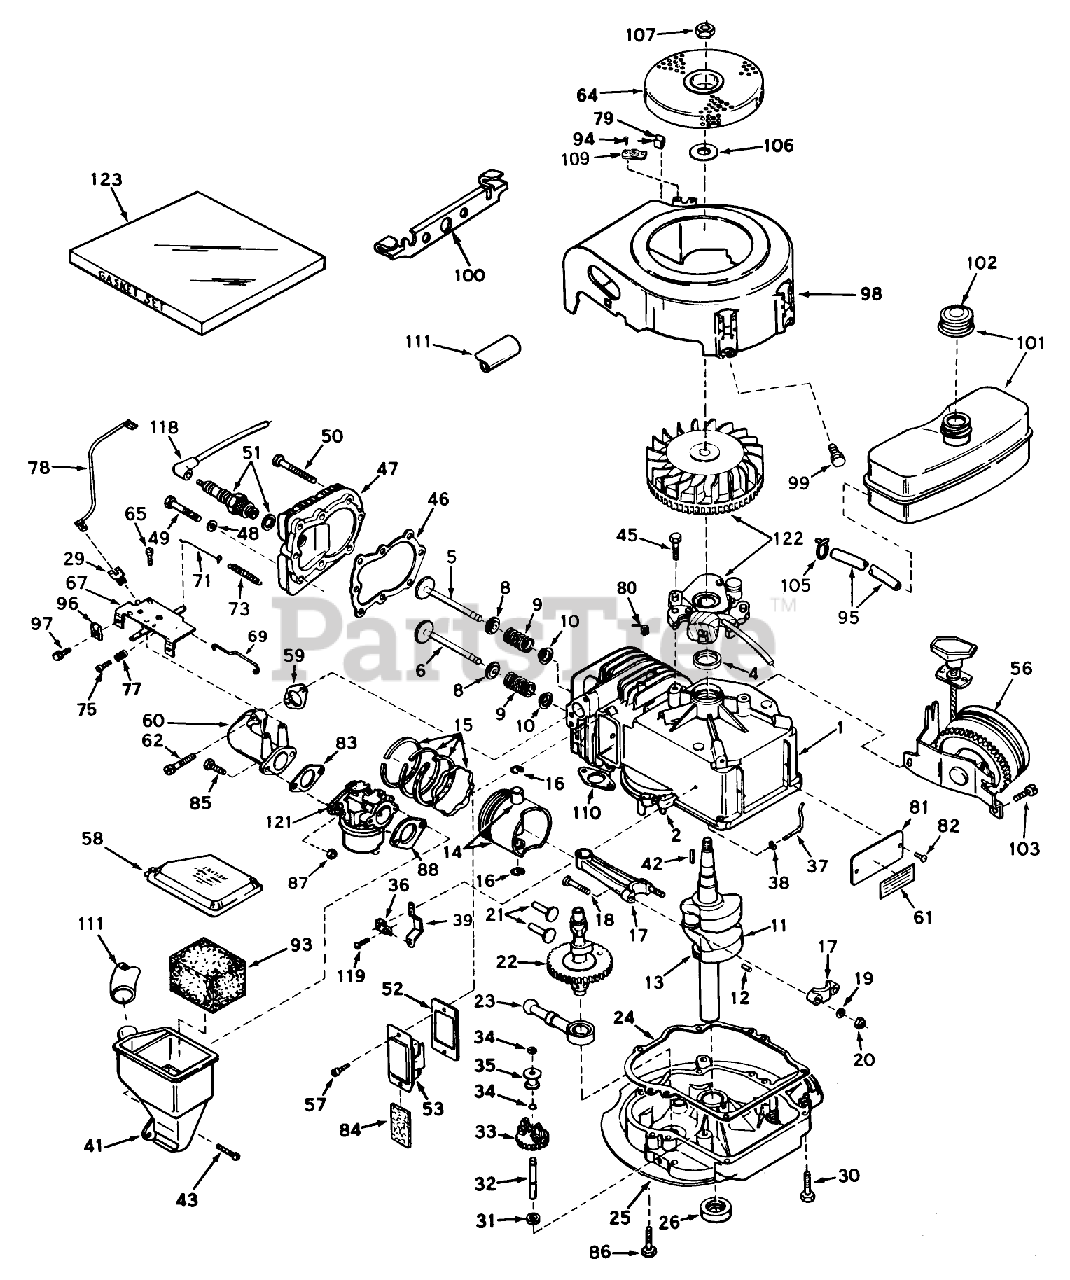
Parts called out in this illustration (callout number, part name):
1	Cylinder Assembly (Incl. Nos. 2, 4 113)
2	Pin-Dowel
4	OIL SEAL
5	Valve, Intake (Incl. Ref. #38, 39 40) (Std.)
5	Valve, Exhaust (1/32" Oversize) (Incl. Nos. 8, 9 10)
6	Valve, Exhaust (Standard) (Incl. Nos. 8, 9 10)
6	Valve, Exhaust (1/32" Oversize) (Incl. Nos. 8, 9 10)
8	Cap-Upper Valve Spring
9	Spring-Valve
10	Cap-Valve, Spring
11	Crankshaft Assy. (Incl. Ref. 12 13)(Model LAV35-40455H)
12	Pin, Groove
13	Gear, Crankshaft
14	Piston Pin Assembly (Incl. 2 of No. 16) (Std.)
14	Piston Pin Assembly (Incl. 2 of No. 16) (.010 Oversize)
14	Piston Pin Assembly (Incl. 2 of No. 16) (.020 Oversize)
15	Piston Ring Set Std.
15	Piston Ring Set .010 O.S.
15	Piston Ring Set .020 O.S.
16	Ring-Retaining, Piston Pin
17	Rod Assy., Connecting (Incl. Ref. #17)
18	Bolt, Connecting
19	Washer
20	LOCKNUT
21	Lifter-Valve
22	Camshaft (Compression Release
23	Oil Pump ASM
24	Gasket, Mounting
25	Flange Assy., Mounting (Incl. #26 32)
26	Seal Oil
29	Terminal
30	Screw (1/4-20 x 1-1/4)
31	Washer-Flat
32	Shaft-Governor
33	Governor Gear ASM
34	Ring-Retaining
35	Spool-Governor
36	Clamp-Lever, Governor
37	Rod, Governor (Incl. No. 36)
38	Washer-Flat
39	Governor Lever
41	Body, Air Cleaner
42	Key Flywheel
43	Screw, Fil. Hd. Sems
45	Screw
46	Gasket-Cylinder Head
47	CYLINDER HEAD
48	Washer
49	Screw
50	Screw Hex Hd. Cap
51	Plug, Spark (J17LM or equiv.)
52	Gasket Breather
53	Breather Assembly (Incl. Nos. 52 84)
56	Starter, Side Mount
57	Screw
58	Cover, Air Cleaner
59	Gasket, Intake
60	Pipe, Intake
61	480B GIL SNWTHWR O/
62	Screw (1/4-20 x 1)
64	Screen, Flywheel
65	Screw (10-24 x 9/16)
67	51089 SUPP TO MANUA
69	Link Governor
71	Link-Governor
73	Spring, Governor
75	Screw
77	Spring-Compression
78	Wire, Ground
79	51004 GIL ROTARY TI
80	Clip-Wire
81	IDENTIFICATION PLATE
82	Stud
83	Gasket
84	Element-Breather
86	Screw
87	Nut and Lock Washer (1/4-28)
88	Gasket-Air Cleaner
93	Element, Air Cleaner
94	Rivet
95	Line-Fuel (8.62)
96	Conduit
97	Screw (10-32 x 3/8)
98	Housing, Blower
99	Screw (1/4-20x19/32)
100	Bracket, Shroud
101	Tank, Fuel
102	Cap, Fuel Filler
103	Screw (1/4-20 x 1/2)
105	Clamp-Line, Fuel
106	Washer
107	Hex Nut
109	Bracket Assy.
110	Gasket Exhaust
111	Tube, Air Cleaner
118	Cover-Spark Plug
119	Screw
121	Carburetor (Incl. No. 83)
122	Magneto
123	Gasket Set
